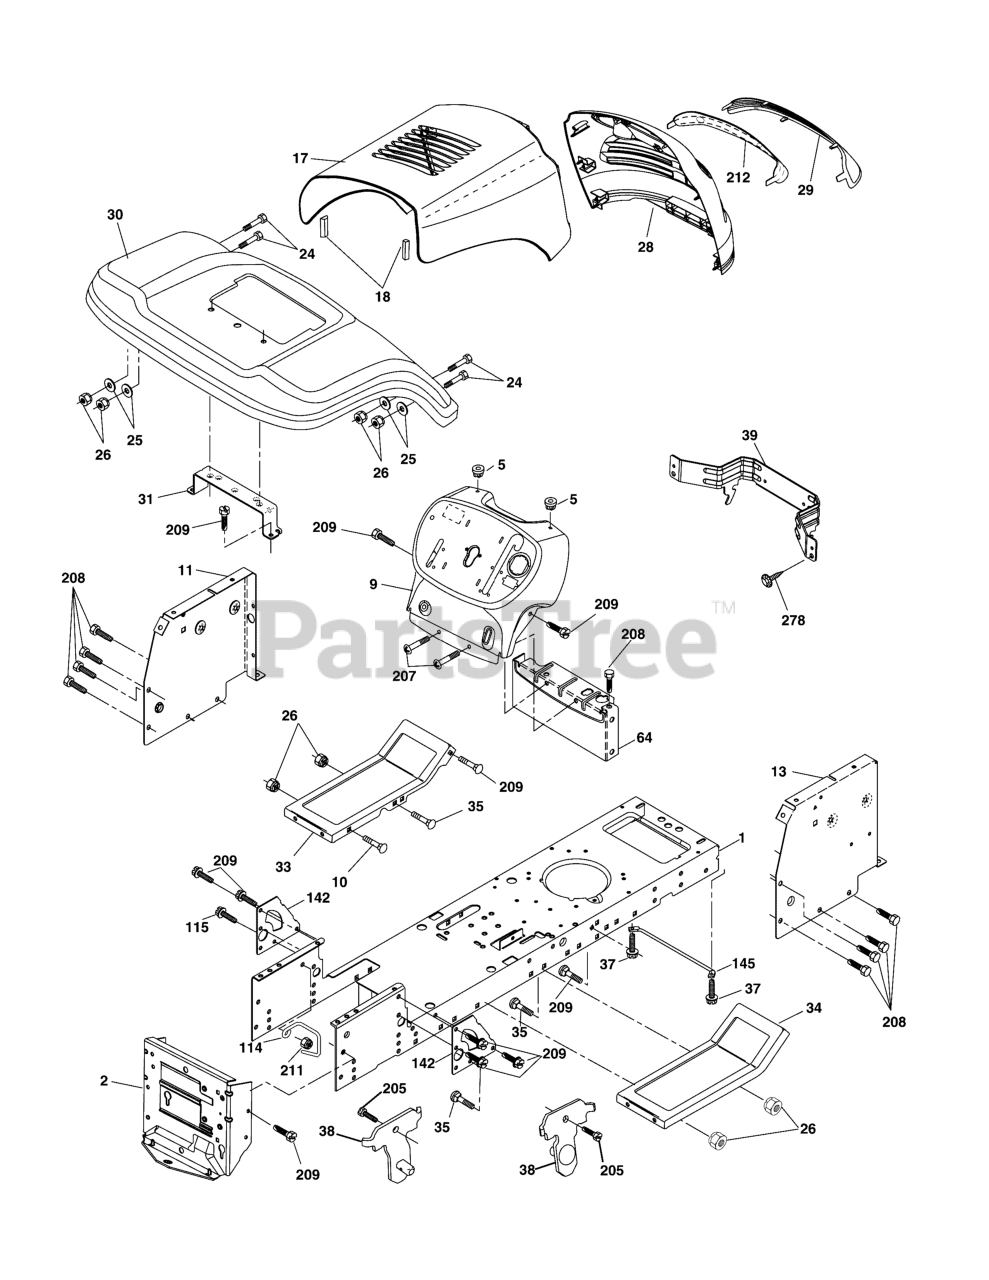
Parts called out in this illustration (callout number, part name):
1	Chassis
2	Drawbar, Stretch
5	Bumper, Hood/Dash
10	Bolt, Carriage 3/8-16 x 1
11	Panel Dash LH
13	Panel Slkscr Dash RH
18	Bumper Hood
24	Bolt Fin Hex 3/8-16 unc x 1 Gr. 5
25	Washer 13/32 x 13/16 x 12 Ga.
26	Nut Lock Hex w/Ins 3/8-16 unc
28	Grille
29	Lens Grille Bar
30	Fender
31	Bracket Fender Repl 109873X
33	Footrest Pnt LH
34	Footrest Pnt RH
35	Bolt Rdhd Sht Sqnk 3/8-16 x 3/4
37	Screw Thdrol 5/16-18 x 1/2 TYT
38	Bracket Asm. Pivot Mower
39	Bracket Pivot
64	Dash Lower
114	Keeper Belt Rear LH
115	Screw 3/8-16 x 1-1/4
142	Plate Reinforcement
145	Rod Pivot Hood
205	Screw Thdrol 3/8-16 x 1/2
207	Screw 5/16-18 x 1/2
208	Screw Thdrol 3/8-16 x 1/2
209	Screw Hex Wsh Thdrol 3/8-16
211	Nut Hexflange Lock
212	Insert Lens Reflect
278	Screw #10 x 0.750 BOS Thread
